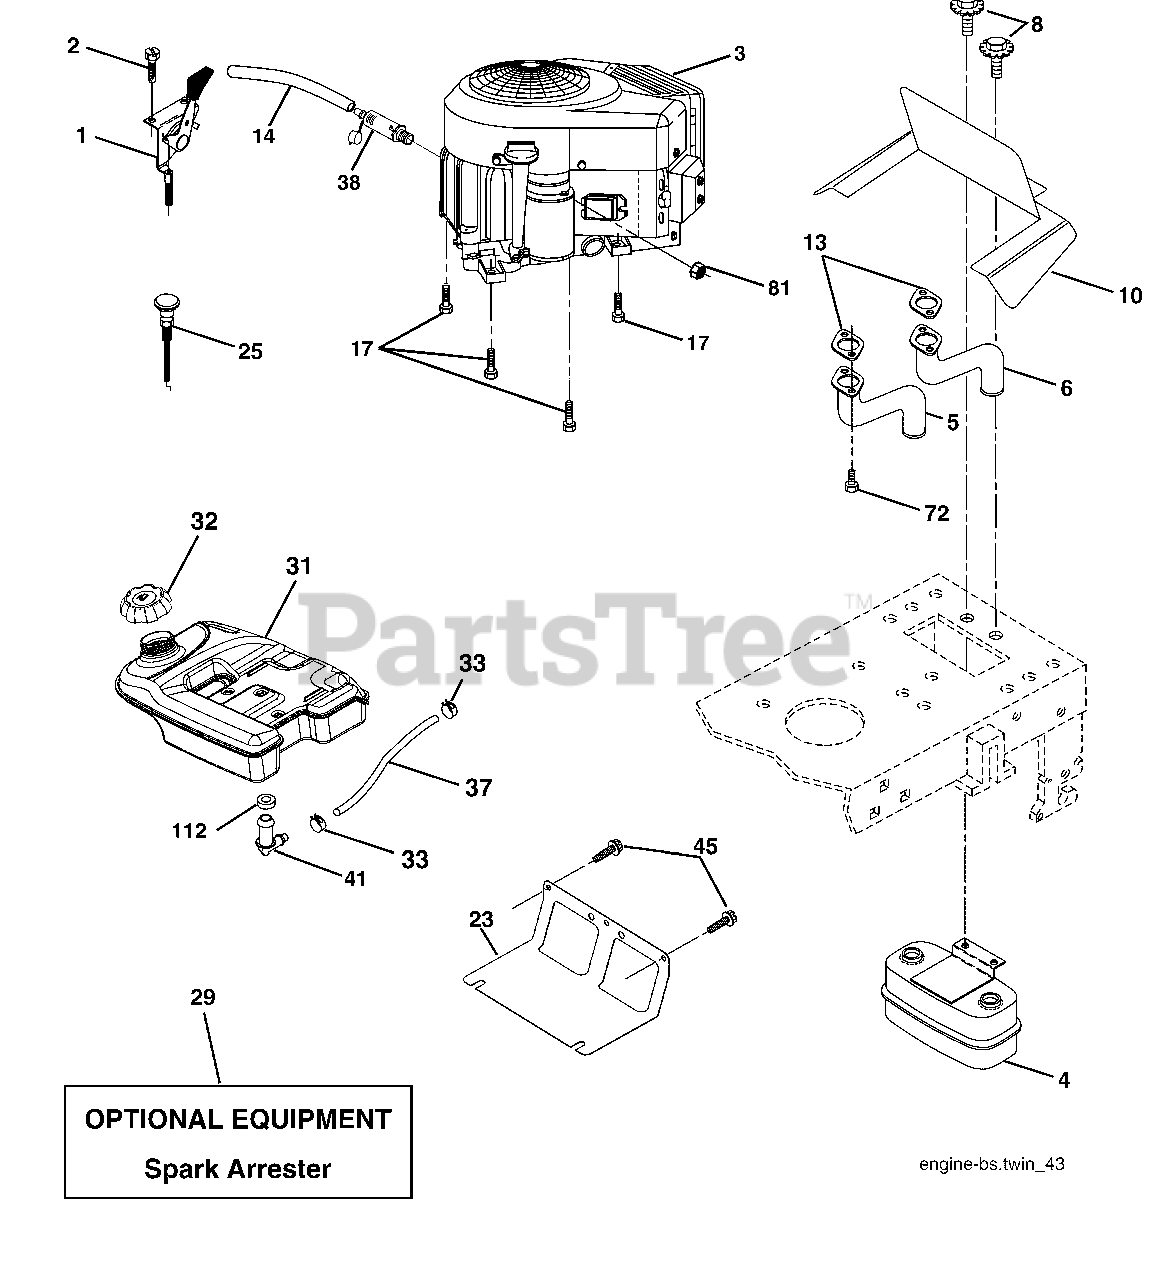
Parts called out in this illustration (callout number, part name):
1	Control Th/ch Flag
2	Screw Hex Thd Cut 1/4-20 x 1/2
5	Exhaust Tube LH
6	Exhaust Tube RH
8	Bolt 5/16-18 unc x 3/4
10	Shield Heat Muffler
14	Tube Drain Oil Easy
17	Screw 3/8-16 x 1-1/2
23	Shield Browning/Debris Guard
25	Control Choke
29	Kit Spark Arrestor
32	Cap Asm Fuel
33	Clamp Hose Black
37	Line Fuel
38	Plug Drain Oil Easy
41	Stem Tank Fuel
45	Screw Hex Wsh Thdr 3/8-16 x 3/4
72	Screw Socket Head 5/16-18 x 1
81	Nut Keps Hex 1/4-20 Starter Nut
112	Bushing
